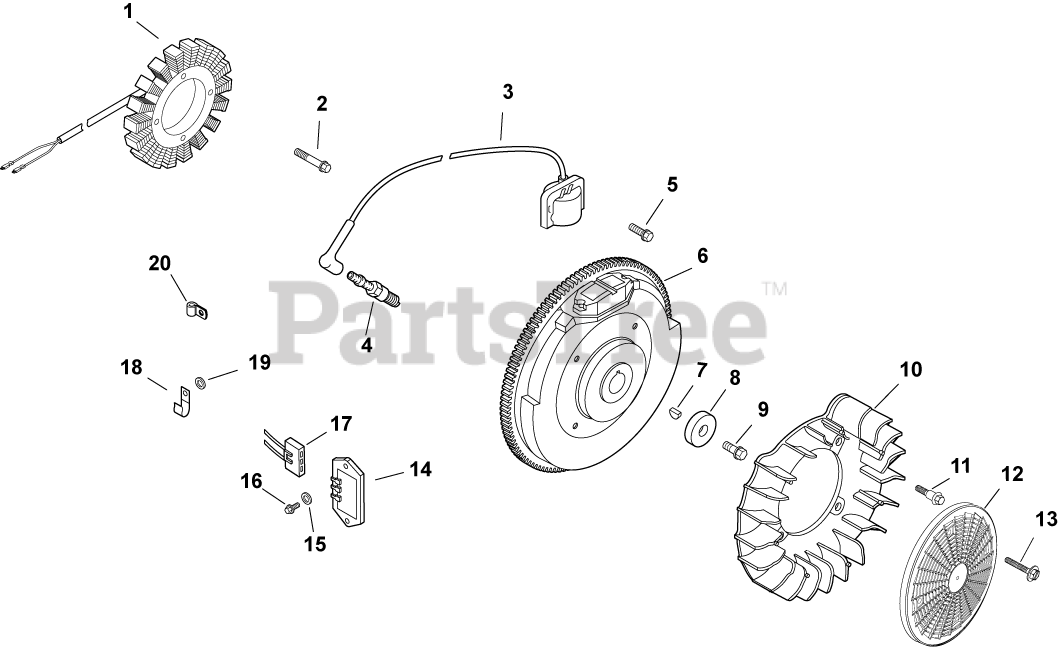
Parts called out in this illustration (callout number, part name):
1	KIT, 15 / 20 AMP STATOR
2	SCREW, M5X0.8X25 - (#25086402S)
3	KIT, MODULE IGNTN (CDI FIXED)
4	PLUG, SPARK (PRO SERIES)
5	SCREW, FLG THD FRM M5X.8X20-(#25086399S)
6	FLYWHEEL, PAINTED-USE 24 025 59-S
7	KEY, 3/16" X 5/8"
8	WASHER, FLAT 13/32"
9	SCREW, FLG M10X1.5X45 - (#25086361S)
11	BOLT, SHOULDER
12	KIT, GRASS SCREEN
13	SCREW, FLG SEMS M4X.7X25
14	REG/RECTIFIER (20/25 AMP)-USE 25 403 20-
15	WASHER, FLAT 1/4" (O.D. 1/2")
16	SCREW, PHL HD #11-16X7/8"
17	CONNECTOR, BODY (KM)-USE 25 155 41-S
18	CLIP, CABLE
19	WASHER, FLAT 7/32"
20	CLIP, TUBE & WIRING (KM)
2417679-S	HARNESS, WIRING
2545403-S	TIE, WIRE
24126137-S	BRACKET, GROUND STRAP USE 24 518 12-S
